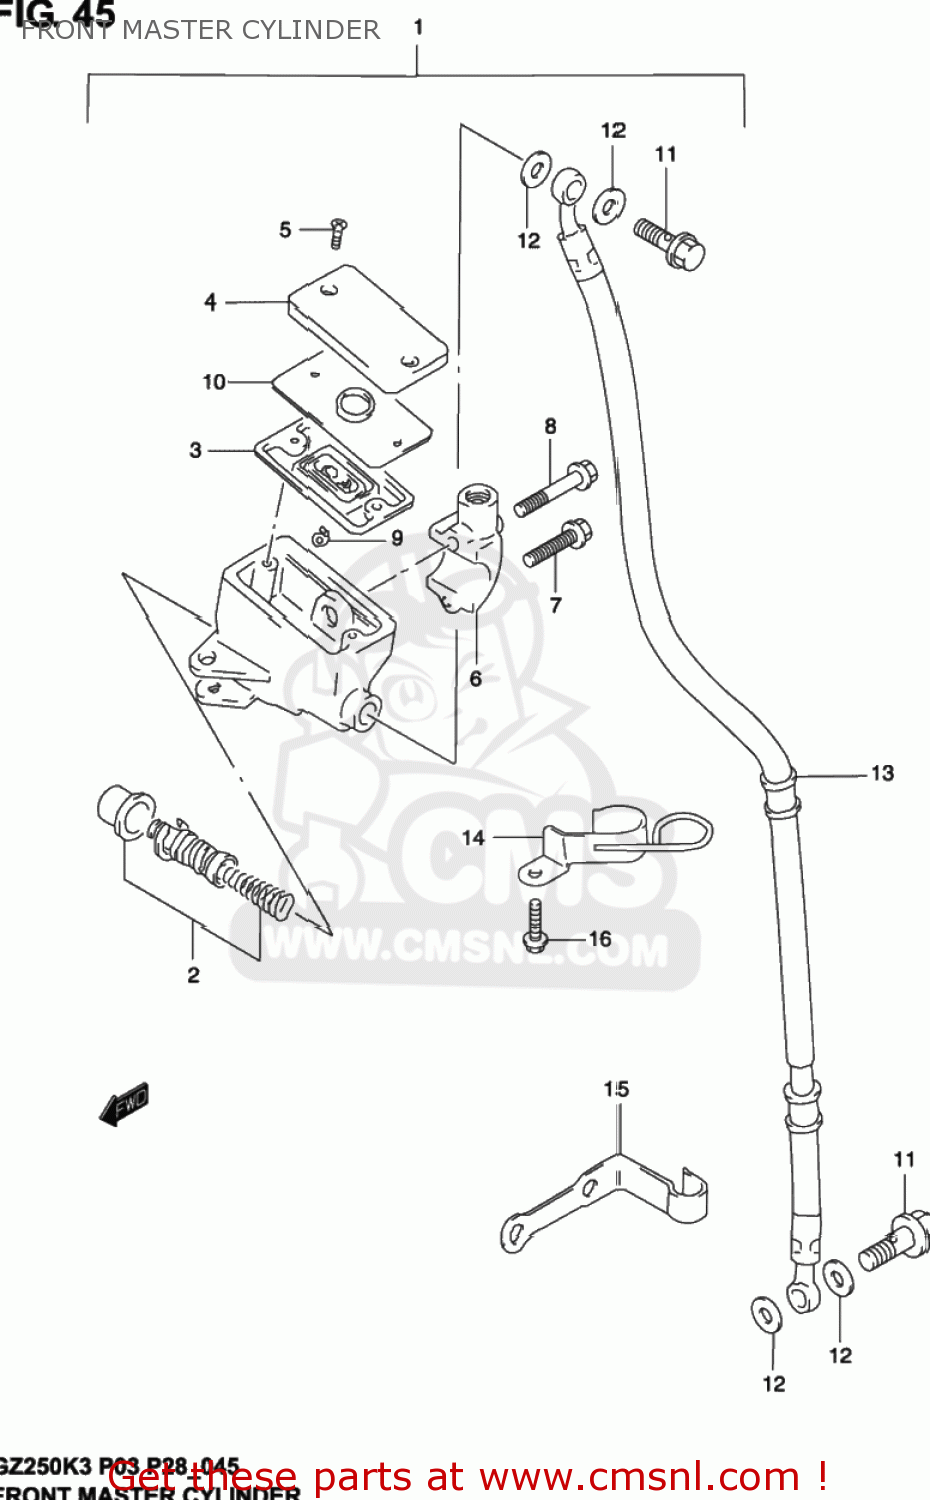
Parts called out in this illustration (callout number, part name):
1	CYLINDER ASSY
2	PISTON/CUP SET
3	DIAPHRAGM
4	CAP
5	SCREW
6	HOLDER
7	BOLT (6X25)
8	BOLT UPPER
9	PROTECTOR
10	PLATE
11	BOLT UNION
12	WASHER(10X15X1.5)
13	HOSE, FRONT BRAKE
14	CLAMP,FR BRAKE HOSE
15	CLAMP,BRAKE HOSE
16	BOLT
